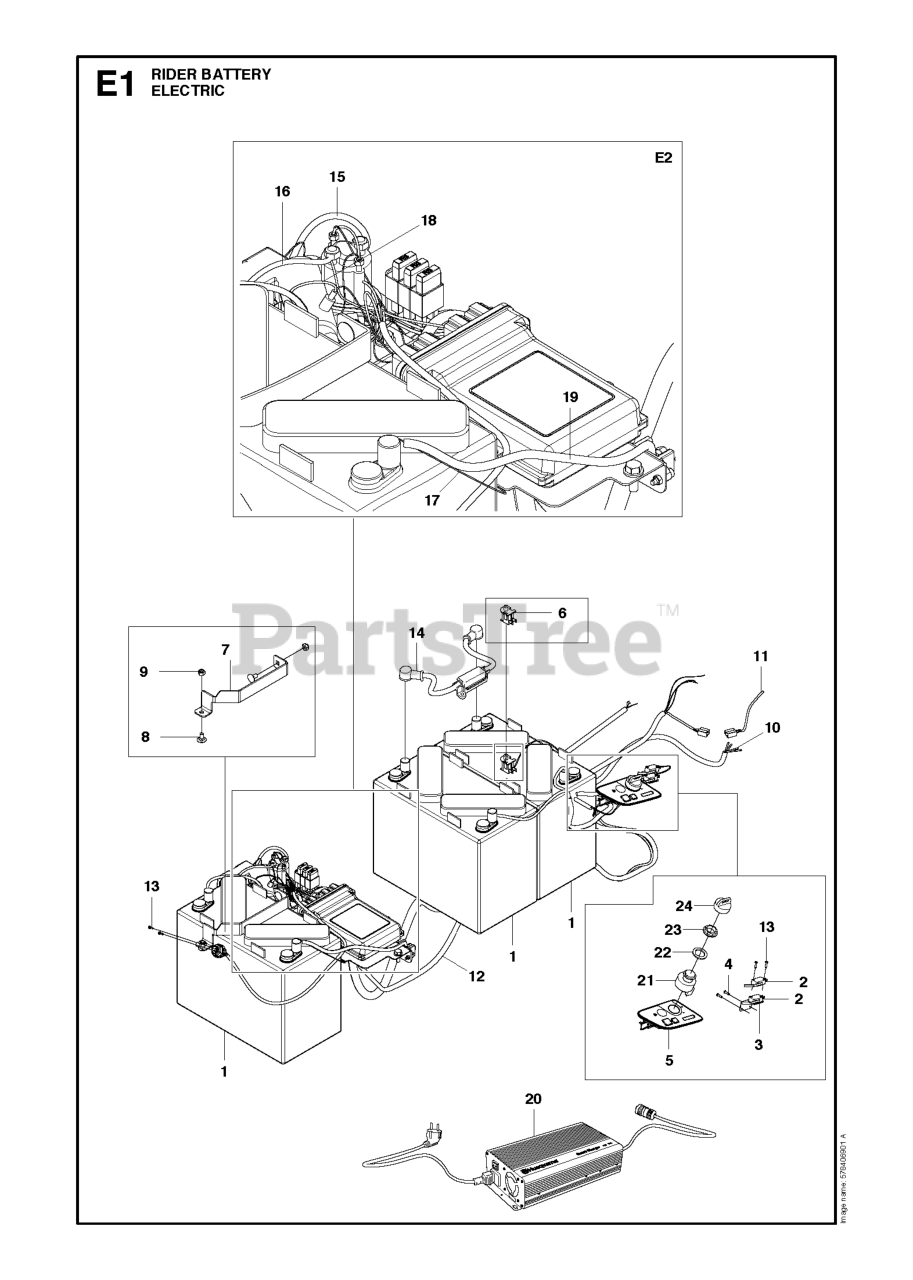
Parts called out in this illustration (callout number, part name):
2	MICRO SWITCH
6	SEAT SWITCH
9	LOCKNUT M8
